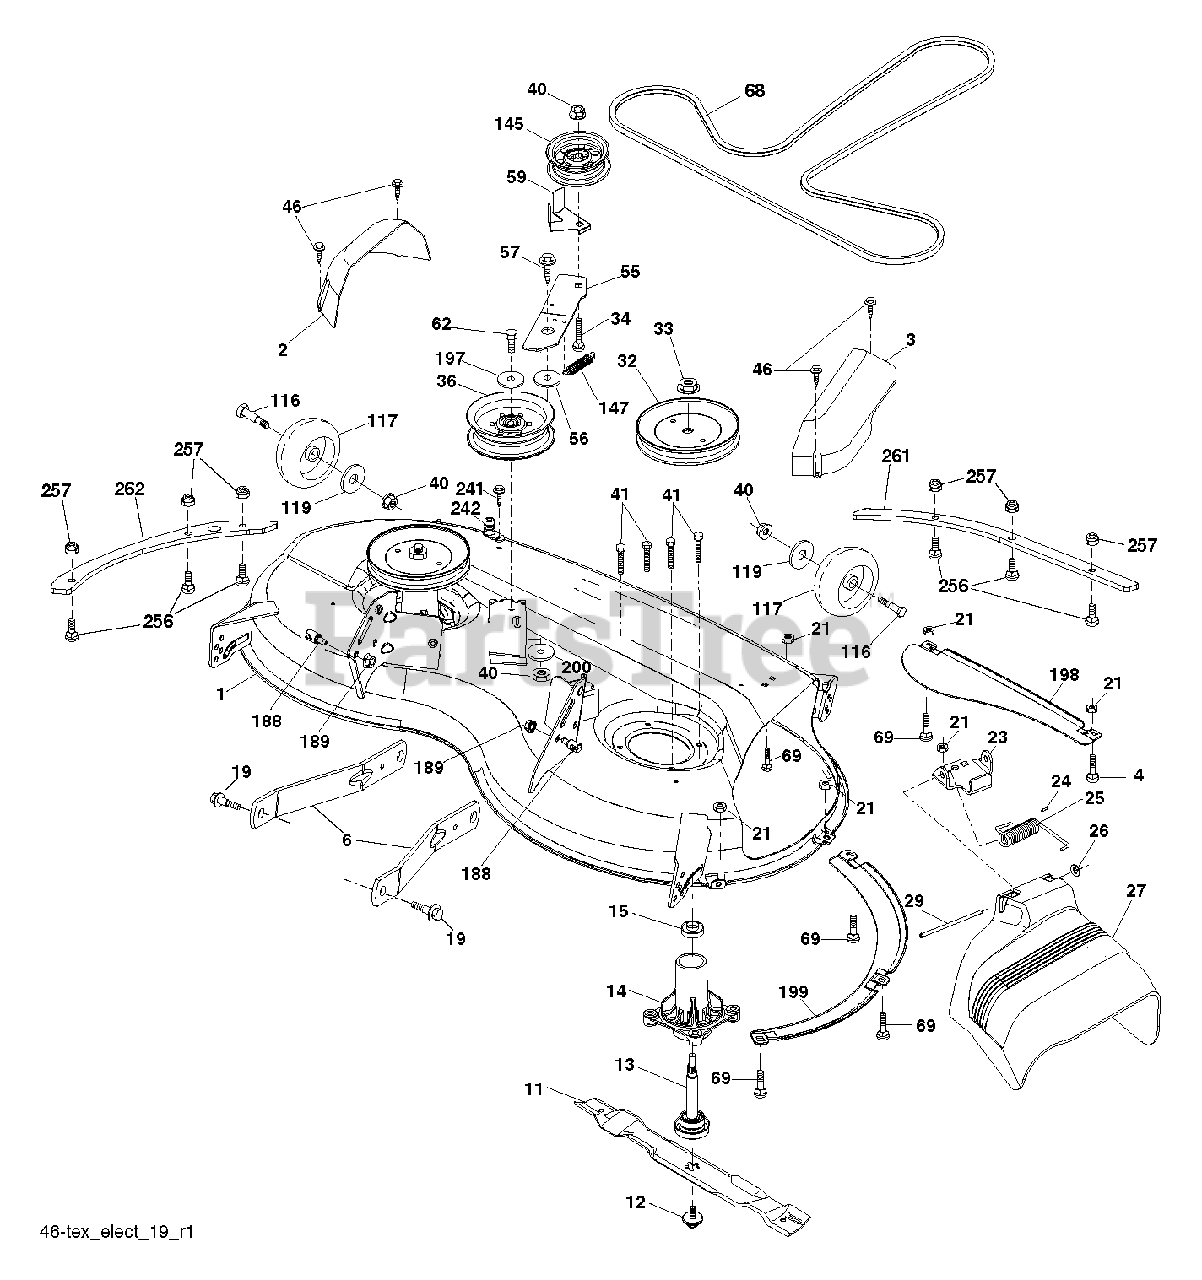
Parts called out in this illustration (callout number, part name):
1	HOUSING.46.WELDMNT.TTR.2GW.498
2	COVER.MANDREL.LH.46"
3	COVER.MANDREL.RH.46"
4	BOLT
6	ARM.SUSPENSION.MOWER.R
11	BLADE.MOWER.46".HI.LIFT
12	SCREW.SEMS.7/16-20X1.HEX.HEAD
13	SHAFT ASM.MNDRL.N/GREASEABLE
14	HOUSING.MANDREL.4PT.
15	BEARING.MANDREL.TOP.EXTENDED
19	BOLT.SHOULDER
21	LOCKNUT
23	BRKT.DEFLECTOR.38"2005+
24	CAP-SLEEVE LT
25	SPRING.TORSION.DEFLECT
26	NUT PUSH M
27	SHIELD.DEFLECTOR.MOWER.46"BLAC
29	ROD.HINGE
32	PULLEY.MANDREL.5.438.PD
33	NUT.FLANGE.LOCK.TOP
34	BOLT.3/8-16X1.50
36	PULLEY.IDLER.2006
40	NUT LOCK FLG 3/8-16 UNC
41	BOLT.HEX.WASHR.HED.313-18X1.19
46	SCREW.1/4-20X5/8
56	SPACER.RETAINER
57	SCREW 3/8-16X1
59	GUARD, BELT
62	BOLT-HEX EAK
68	V-BELT
69	BOLT
116	BOLT M
117	WHEEL.GAGE.HALF.SPOKED
119	WASHER
145	PULLEY.IDLER.48"PRIMARY
147	SPRING.MOWER.DRIVE.ELECTRIC
188	STUD.FASTNER.W/ANTI-ROTATE
189	NUT LOCK HEX FLANGE 5/16-18
197	WASHER
198	BAFFLE CENTER FRONT
199	BAFFLE FRONT RH
200	WASHER.13/32 X 1 X 1/2.11GUARD
241	SCREW.TT.#10-32X.5.3/8.FLANGE
242	PORT.WASHOUT
256	SCREW.BUTTONHEAD.1/4-20X1
257	NUT T
261	PLATE.PNT.REINF.DECK.46".EDIP
262	PLATE.REINFOR.46.SIDEBOLT.X431
